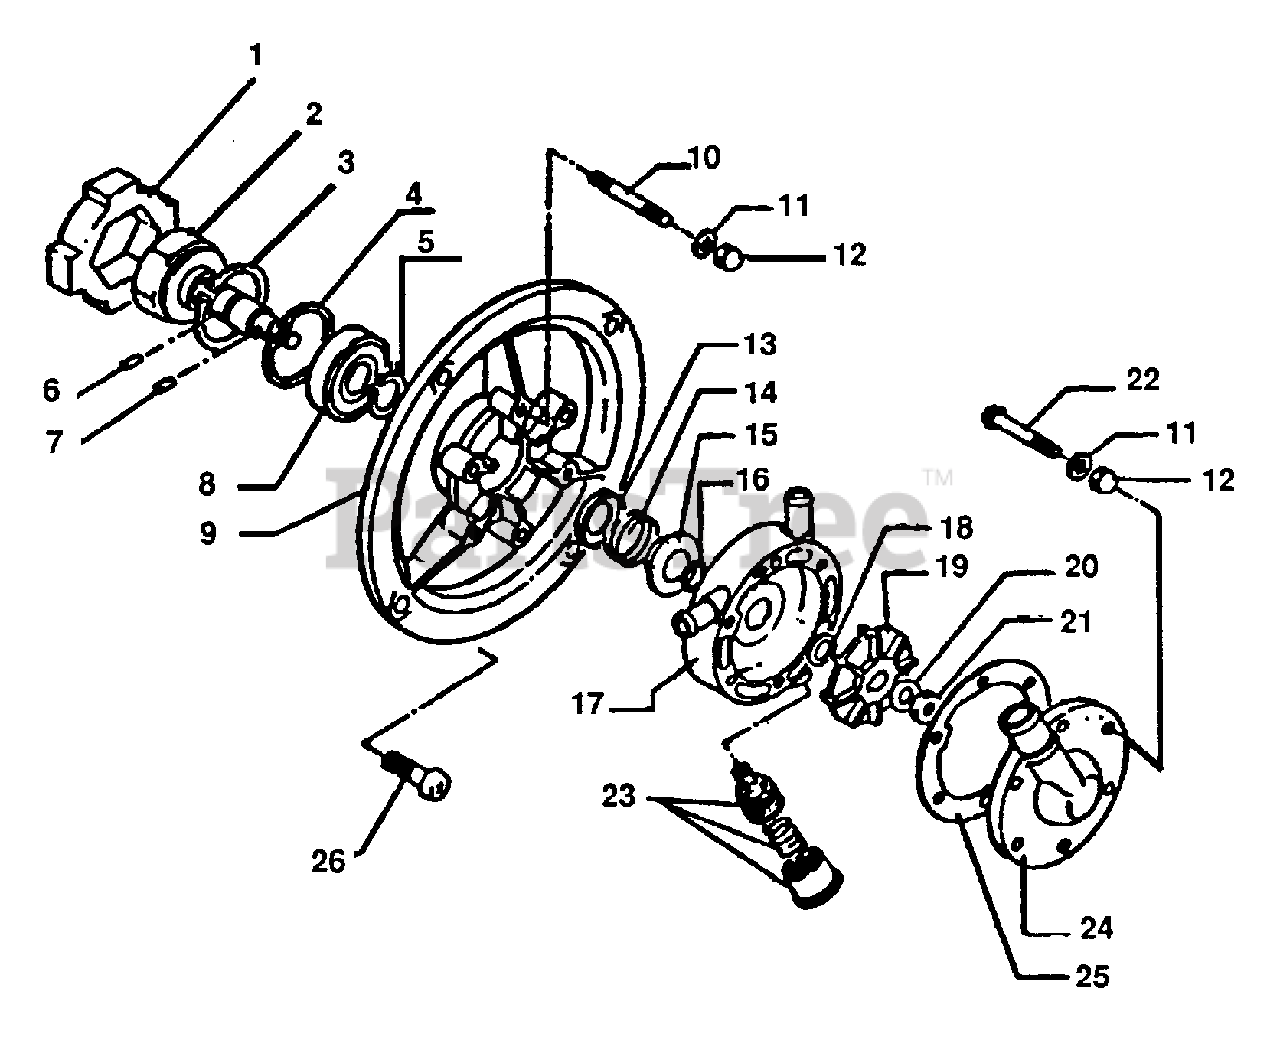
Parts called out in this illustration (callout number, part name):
1	CONNECTOR
2	SHAFT
3	RING, RETAINING - 30
4	RING, SNAP Ø32
5	RING, RETAINING - 12
6	PIN
7	PIN
8	BEARING, BALL 6201-ZZ
9	BASE, PUMP
10	STUD
11	WASHER 4 MM
13	RETAINER
14	SPRING
15	SEAL
16	O-RING 9 MM
17	BODY, PUMP
18	WASHER
19	IMPELLER
20	WASHER 6.5×11.5×0.8
21	NUT - 6
22	SCREW 4×38
23	CUP ASSY, GREASE
24	LID
25	GASKET, PUMP
26	SCREW 6×15
